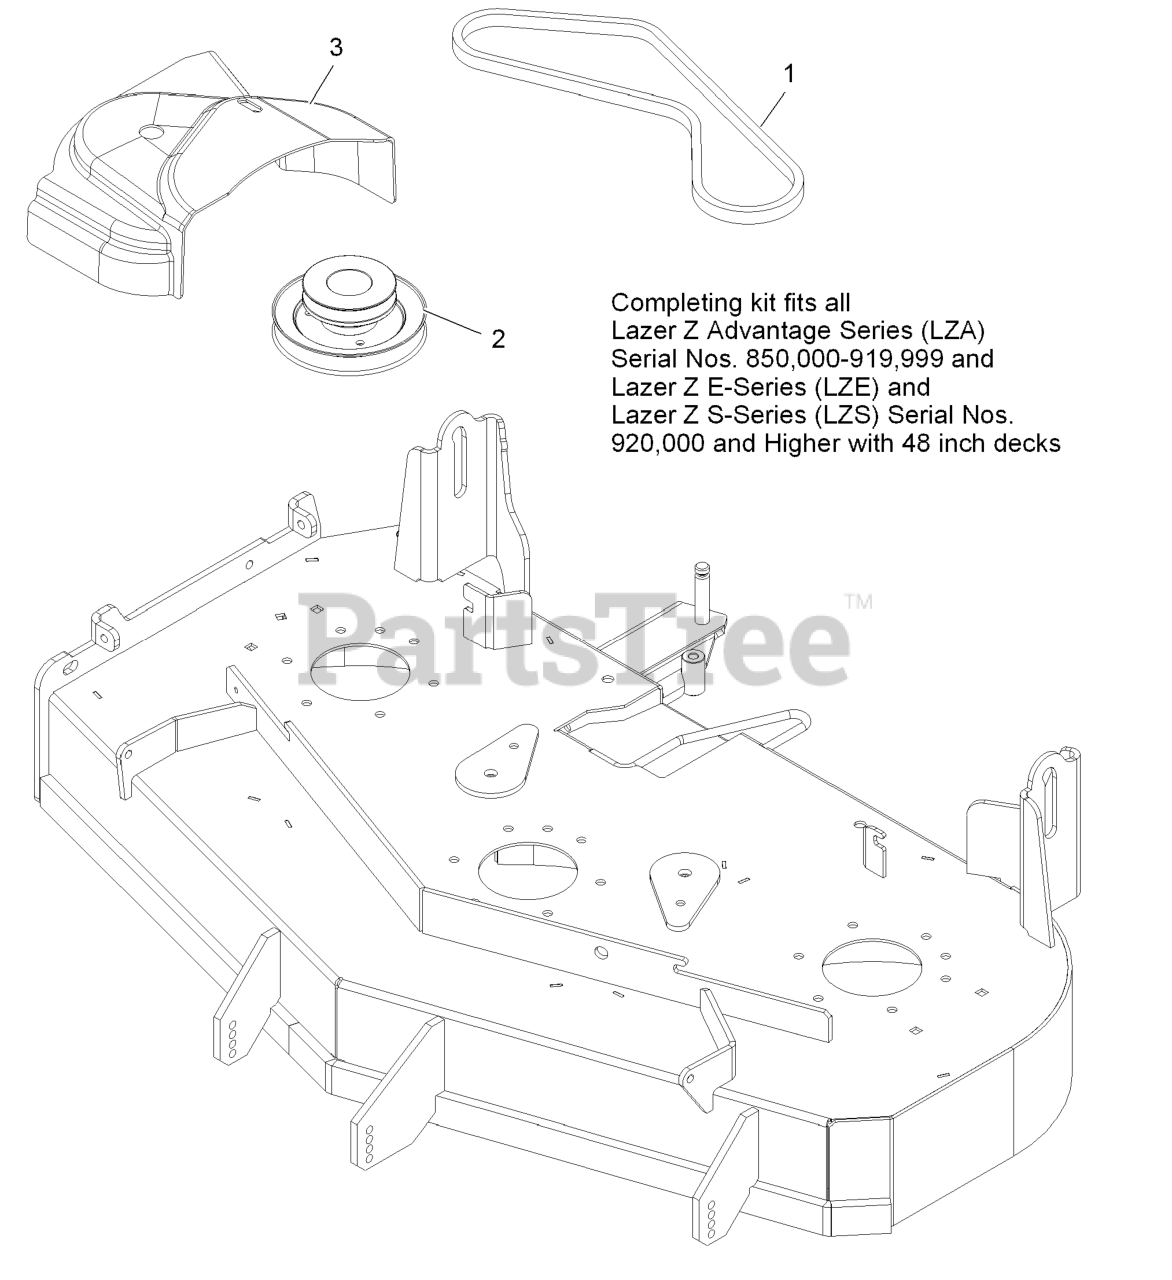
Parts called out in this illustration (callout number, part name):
1	Belt, Blower (48")
2	Jackshaft-Uv Drive, 484 Splined
3	Cover,Belt Uv 48
